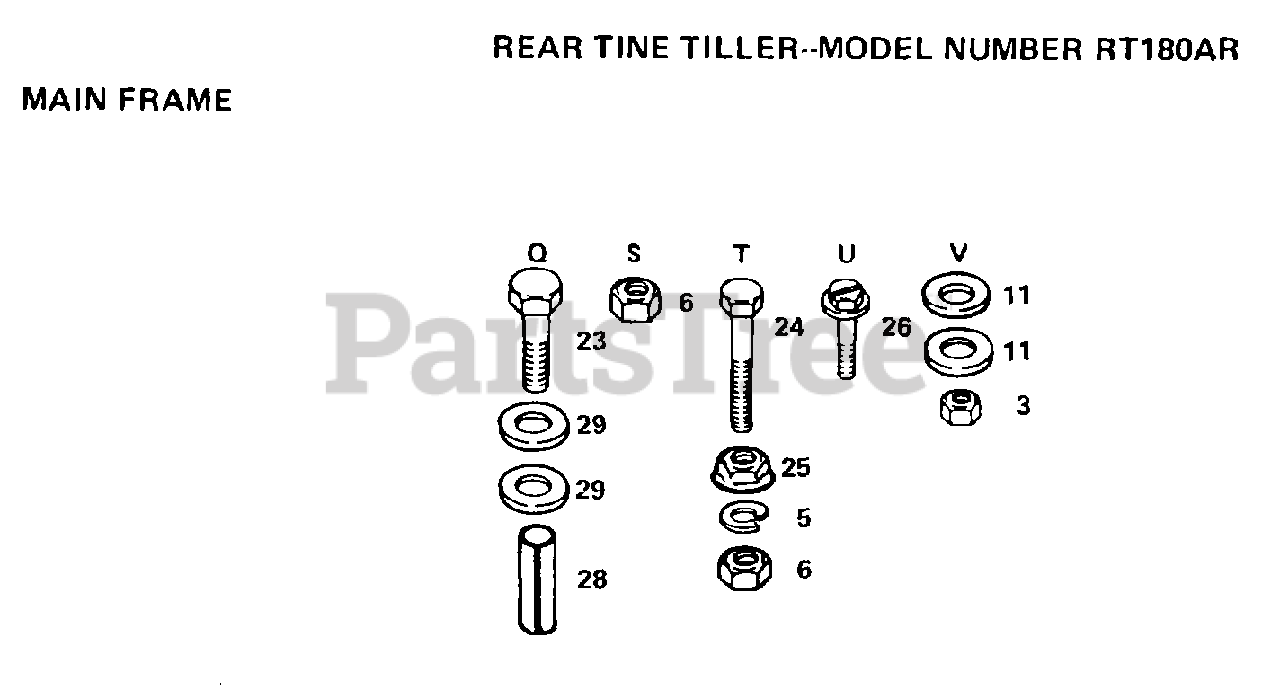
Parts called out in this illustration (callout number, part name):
3	NUT.HEX.5/16-18
5	LOCKWASHER
6	NUT.HEX.3/8-16UNC
11	WASHER
26	SCREW TI
